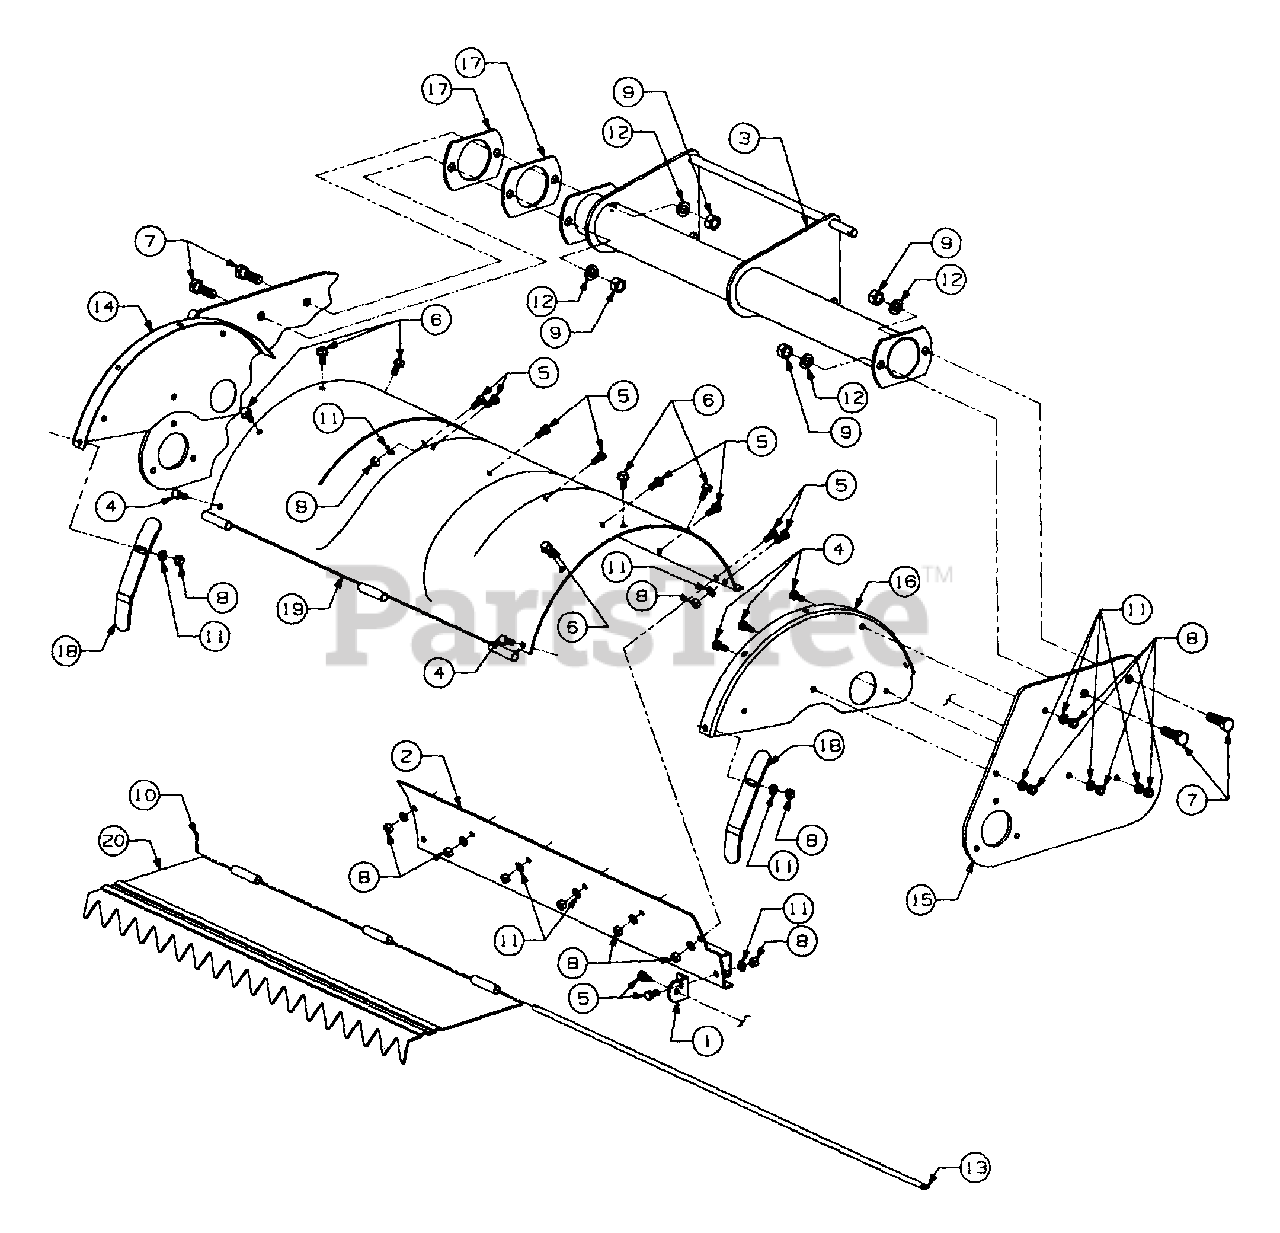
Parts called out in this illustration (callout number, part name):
1	Bracket, Chute Pivot
5	Screw, Hex Cap, 5/16-24 X .62 Lg
6	Screw, Hex Wash TT-Tapp 5/16-18 X .62 Lg
7	Screw, Hex Cap, 1/2-20 X 1.50 Lg GR5
8	Nut, Hex, 5/16-24
9	Nut, Hex, 1/2-20
10	Pin, Cotter, 1/8 Dia X 1.0 Lg
11	Washer, Lock, 5/16
12	Washer, Lock, 1/2
13	Rod, Tiller Flap, 1/4 Dia X 29.7 Lg
